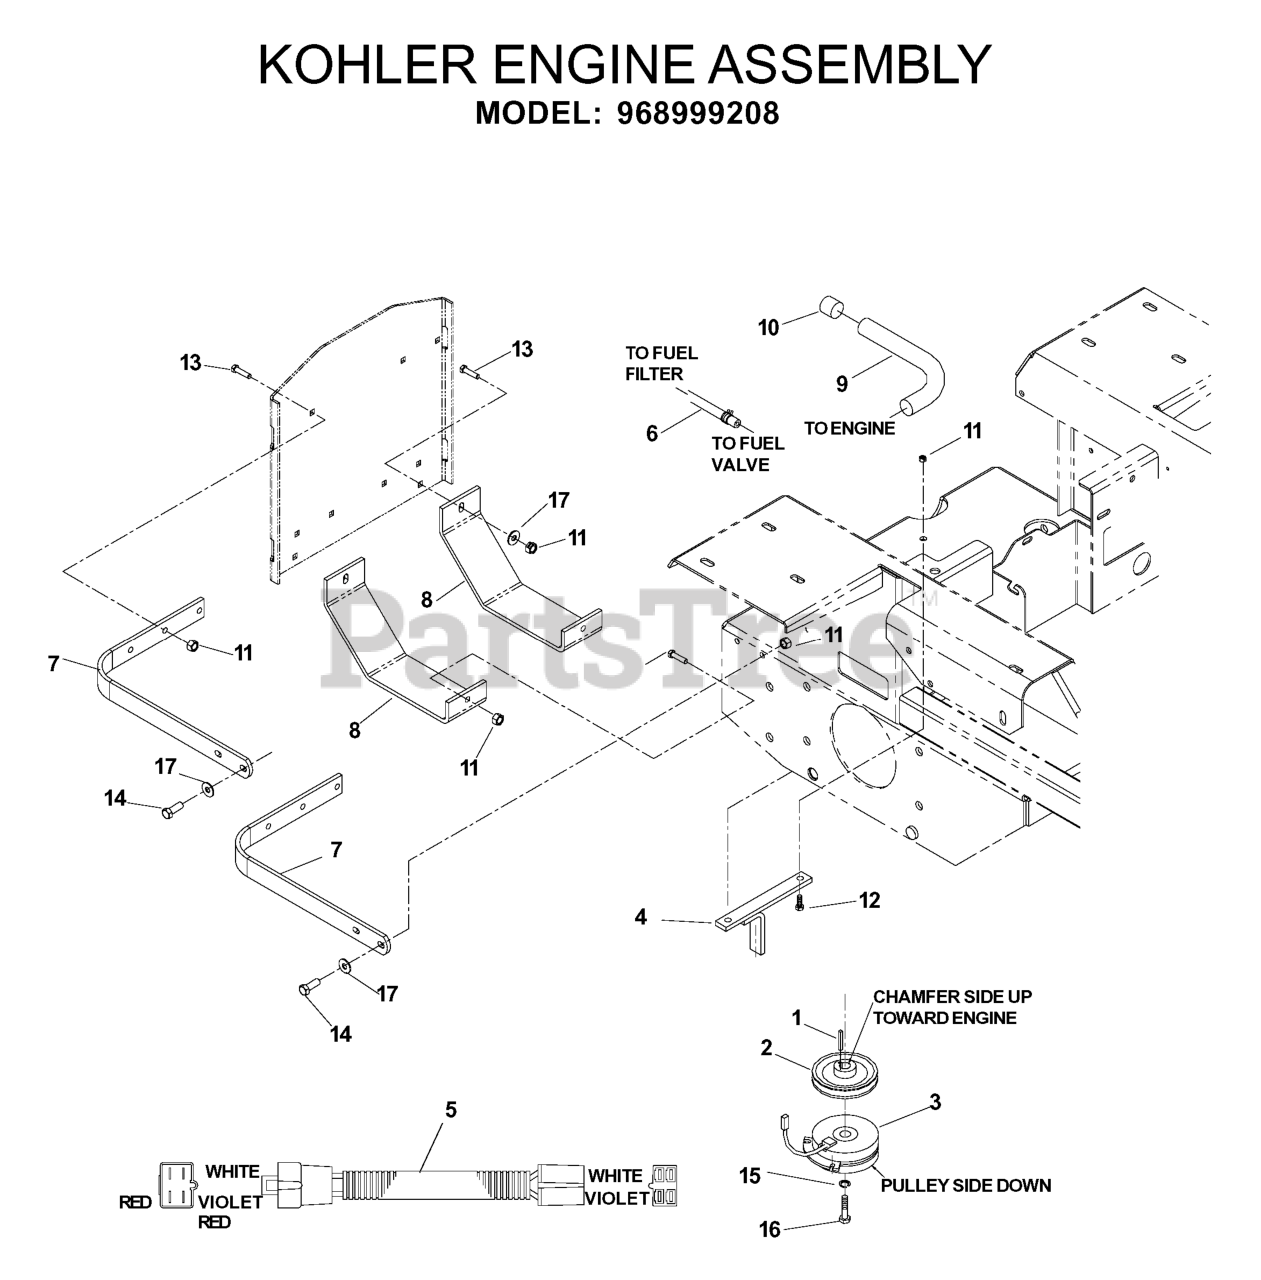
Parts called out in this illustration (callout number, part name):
2	RETURN SPRING
3	THROTTLE LOCK
4	THROTTLE TRIGGER
5	VIBRATION DAMPER
6	STOP BUTTON
8	HANDLE
9	HANDLE
10	VIBRATION ABSORBER
14	VIBRATION ABSORBER
15	THROTTLE HANDLE CPL
16	SHORT CIRCUIT CABLE
17	THROTTLE WIRE ASSY
18	WIRING ASSY.
